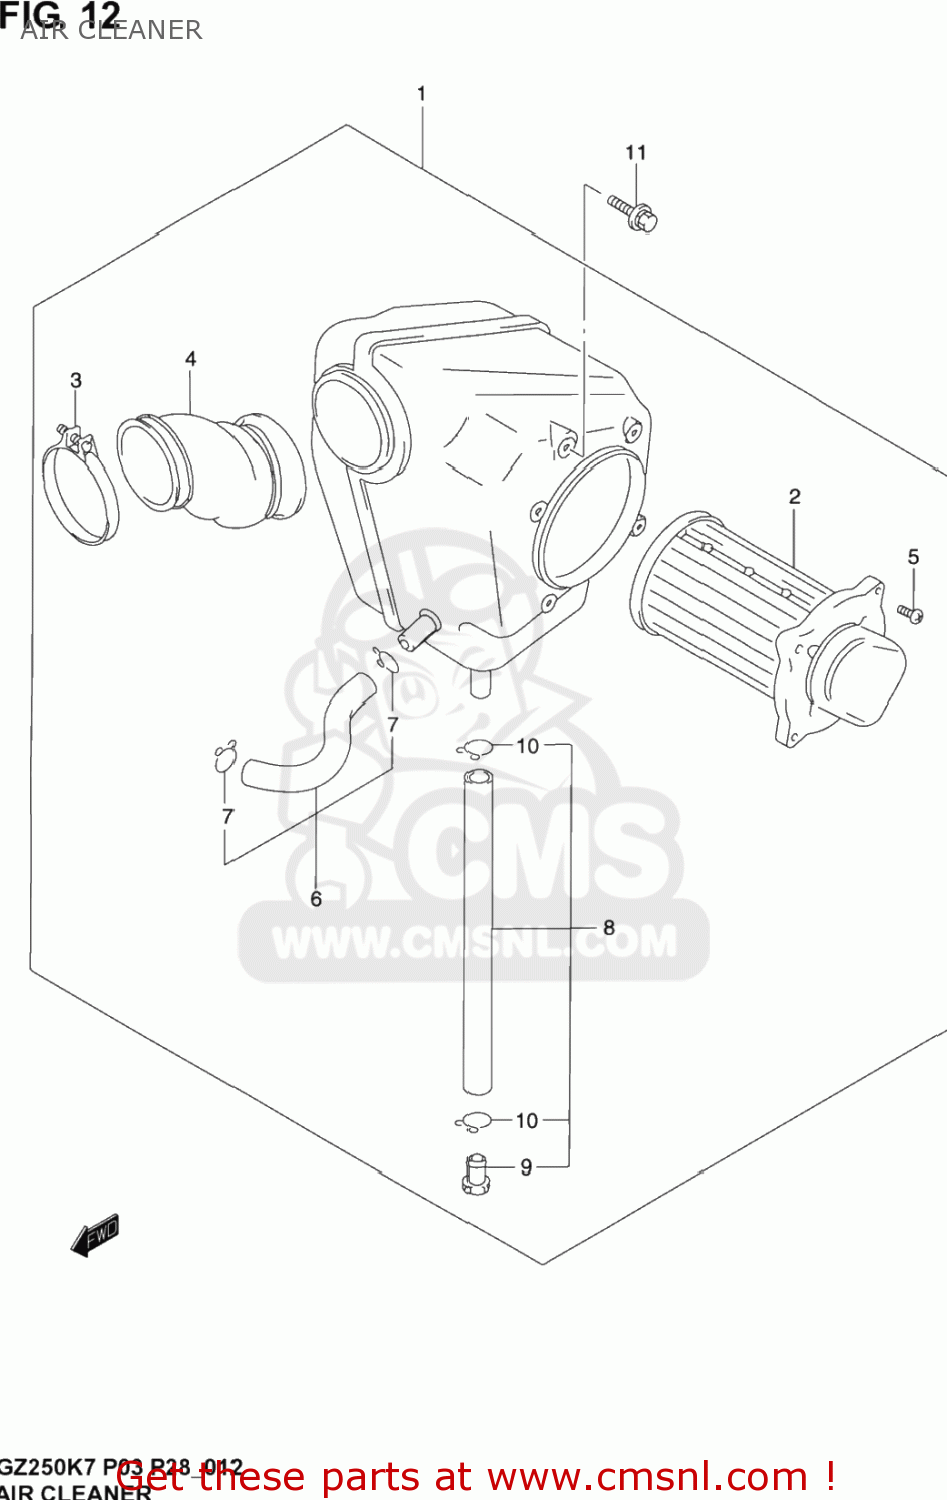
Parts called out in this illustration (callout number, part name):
1	CLEANER ASSY,AIR
2	FILTER,AIR CLEANER
3	CLAMP
4	TUBE,OUTLET
5	SCREW
6	TUBE,BREATHER
7	CLIP
8	TUBE,DRAIN
9	PLUG
10	CLIP
11	BOLT
